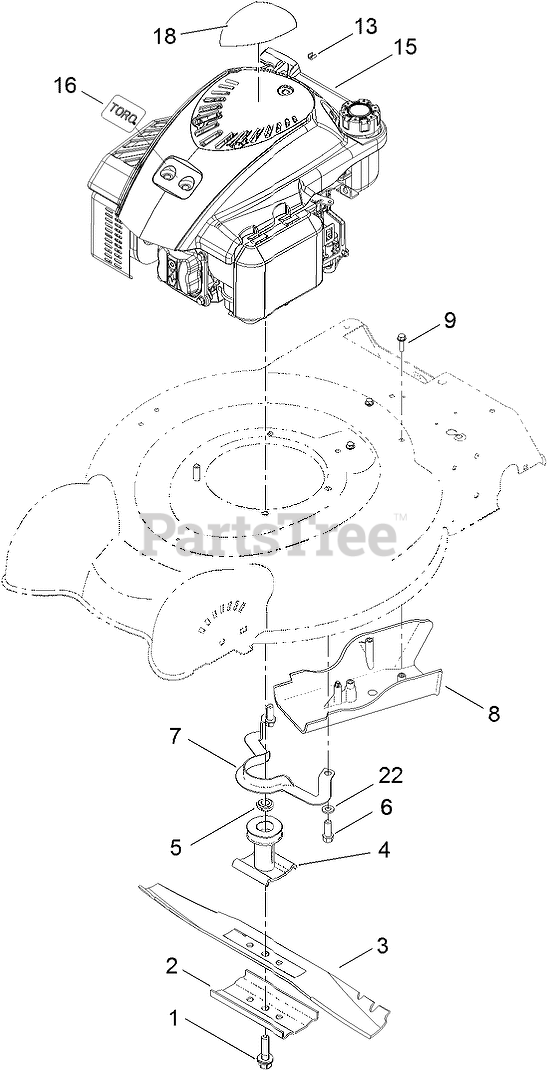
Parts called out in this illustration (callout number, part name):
1	BOLT-BLADE
2	SUPPORT-BLADE
3	BLADE-20 INCH
4	DRIVER-BLADE
5	Spacer-Driver
6	SCREW-TAPTITE
7	Guide-Belt
8	COVER-BELT
9	SCREW-HWH
13	STOP-ROPE
15	ENGINE-LC1P65FA
16	PLATE-LOGO, TORO
18	DECAL-SHROUD
22	WASHER-FLAT
